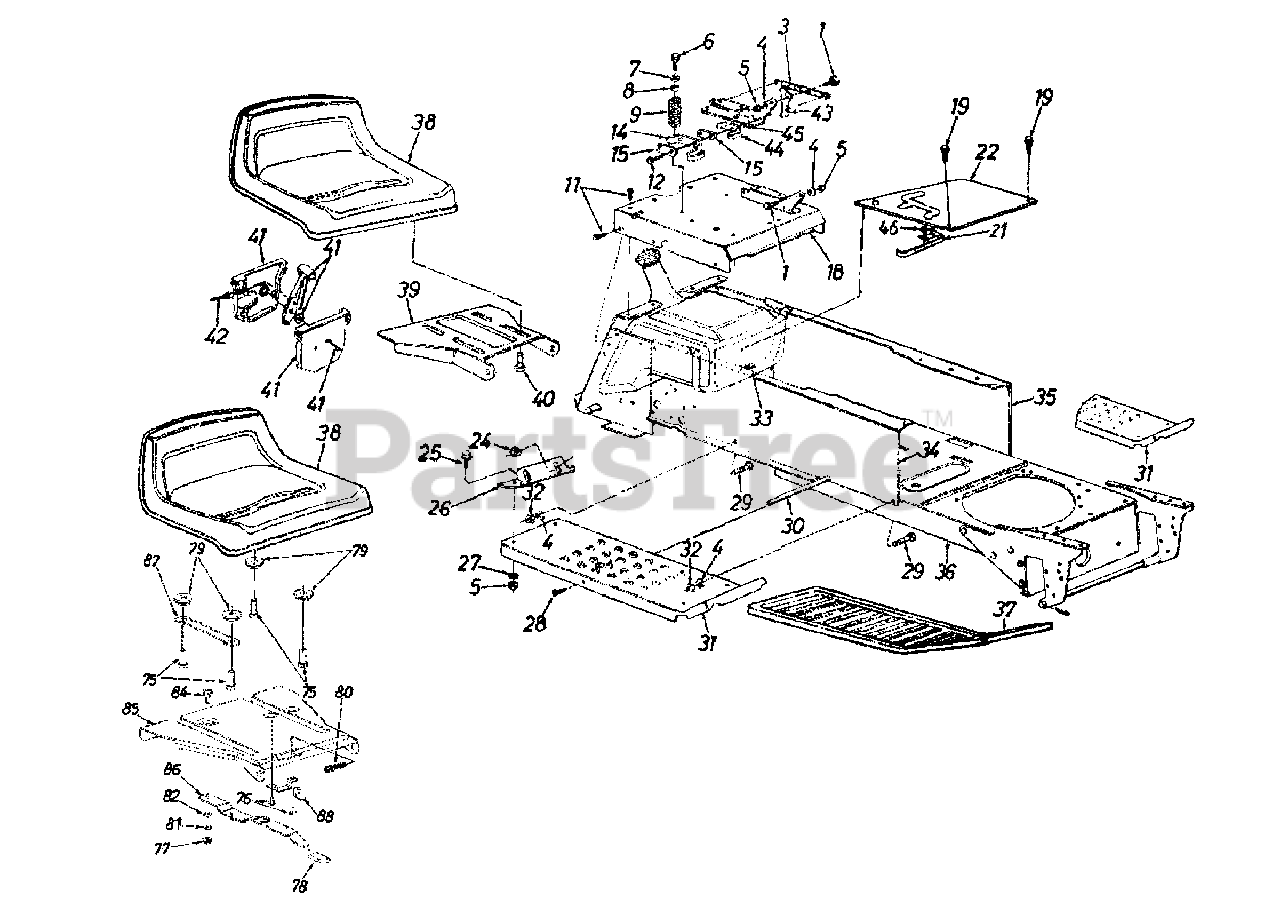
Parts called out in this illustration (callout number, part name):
1	Shld. Bolt .437" Dia. x .162"
3	Ext. Spring 5.31"
4	L-Wash. 5/16" I.D.
5	Hex Nut 5/16-18 Thd. (Gr. 5)
6	Hex Wash. Hd. Tap Scr. 5/16 -18 x .7"
7	Fl-Wash. .344" I.D.
8	Bushing
9	Compression Spring
11	Hx Wash. Hd. AB-Tap Scr. 5/16 x .75"
12	Hx Wash. Hd. AB-Tap Scr. #8 x .5"
14	Spring Switch
15	Insulator Plate
18	Seat Plate
19	Truss Mach. B-Tap Scr.
21	Reverse Safety Switch
25	Hex Bolt 5/16-18 x .75"
28	Truss Mach. Scr. 5/16-18 x .75"
29	Rib Neck Bolt 5/16-24 x .75"
30	Running Board Rod
33	Speed Nut #10Z
38	Seat 8-7/8" High
40	Hex Tap Scr. 3/8-16 x .62"
41	Throttle Control Box Assembly
42	Throttle Control Wire 35"
43	Seat Lift Bracket
44	Seat Spring Switch
45	Insulator Boss Plate
46	Insulator Nut Plate
75	Hex Bolt 3/8-16 x 1"
76	Hx Washer B-Tap Scr. #10-16 x .38"
77	Hex Flanged L-Nut 1/4-20 Thd.
78	Seat Adjustable Grip
79	Spacer
80	Compression Spring 1.5"
81	Spring Wash 265" I.D. x .56" O.D.
82	Fl-Wash. .344" I.D. x .62" O.D.
84	Shld. Bolt .34" x 1/4 -20 Thd.
87	Seat Selector
88	Seat Stop
